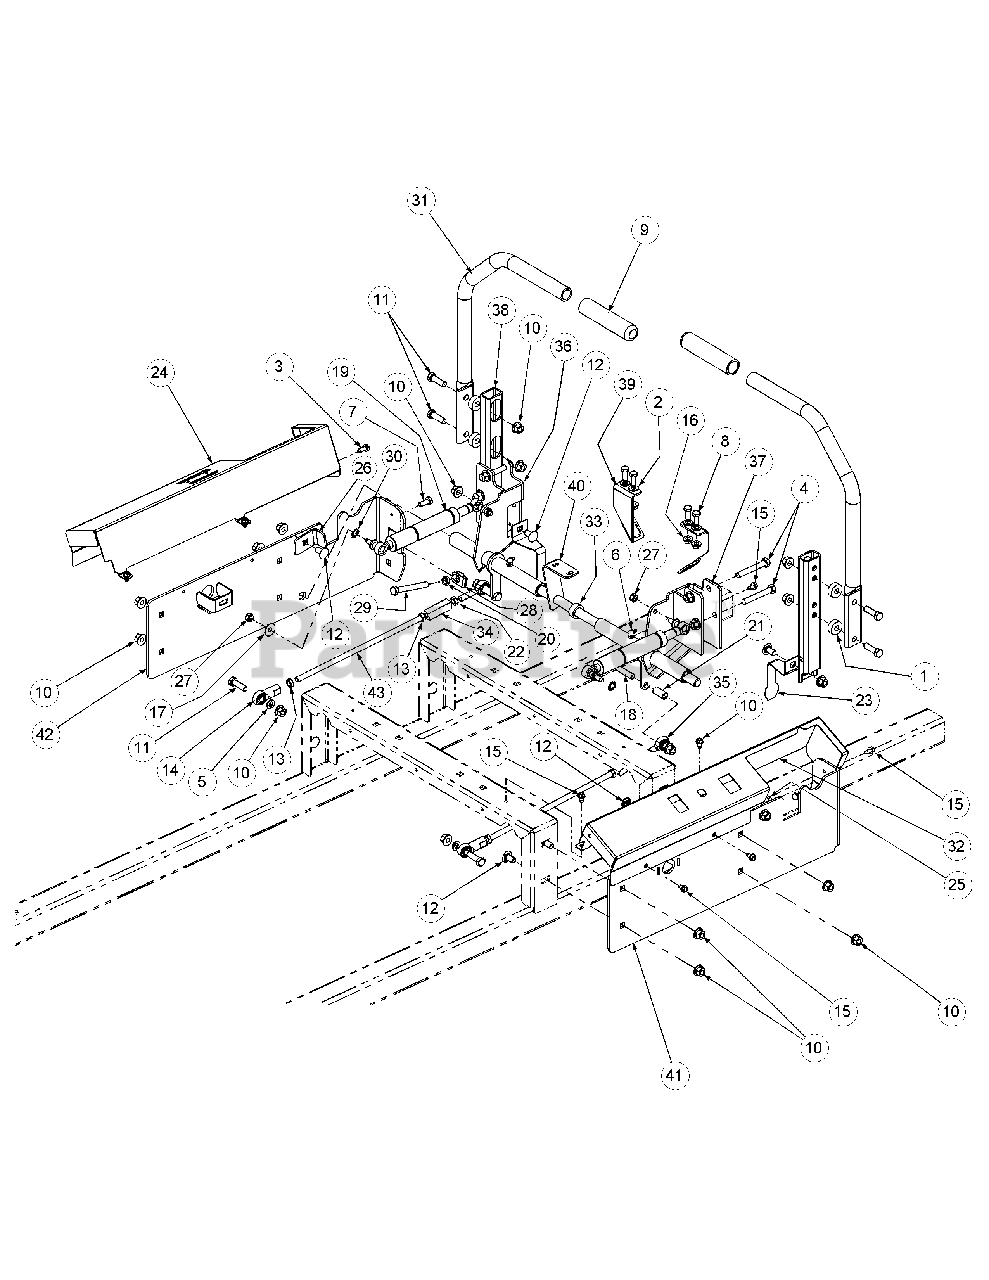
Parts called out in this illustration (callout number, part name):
1	Spacer, .406 ID x 1.00 OD x .38
2	Flat Washer, 5/16
3	Screw, TT, 1/4-20, 0.75, Hex Index Washer
4	Hex Cap Screw, 3/8-16, 2.5
5	Lock Washer, 3/8
6	Grease Fitting, 90°, 1/4-28
7	HHCS, 5/16-18 x 1.0
8	Hex, Cap Screw, 5/16-18 x 3/4
10	Hex Nut, 3/8-16, Lock Flange
11	Hex Cap Screw, 3/8-16, 1.25
12	Carriage Bolt, 3/8-16 x .75
13	Hex Jam Nut, 3/8-24
14	B/Joint, 3/8-24, Right Hand Female
15	Screw, TT, 1/4-20, 0.5, Hex Index Washer
16	Nut, Lock, HexFlange, 5/16-18
17	Belle Washer, .325 x .930 x .045
18	Hex Cap Screw, 3/8-16 x 2.25
19	Cylinder Return to Neutral
20	Nut, 3/8-16, Jam
21	Spacer, .375 x .50 x 1.02
22	Nut, 3/8-24, Jam, LH Third
23	Lever, Safety Switch
24	Control Panel, LH
27	Nut, Hex, Center Lock, M8 x 1.2
28	U-Nut, 3/8-16 x .75
29	HHCS, 3/8-16, 3.00
30	External Lock Washer
31	Lapbar Handle, One Position
32	Control Panel, RH
33	Shaft Collar, .625 ID, 1.00 OD, .438 Lg
34	Turnbuckle
35	B/Joint, 3/8-24, Left Hand Female
36	Hub Assy, Control LH Bearing
37	Hub Assy, Control RH Bearing
38	Mounting Handle
39	Switch Mounting Bracket, Lapbar
40	Shaft Control Brake Steering
41	Side Panel, Control, Right
42	Side Panel, Control, Left
43	Rod Connector, 3/8-24 x 11.00 Long
